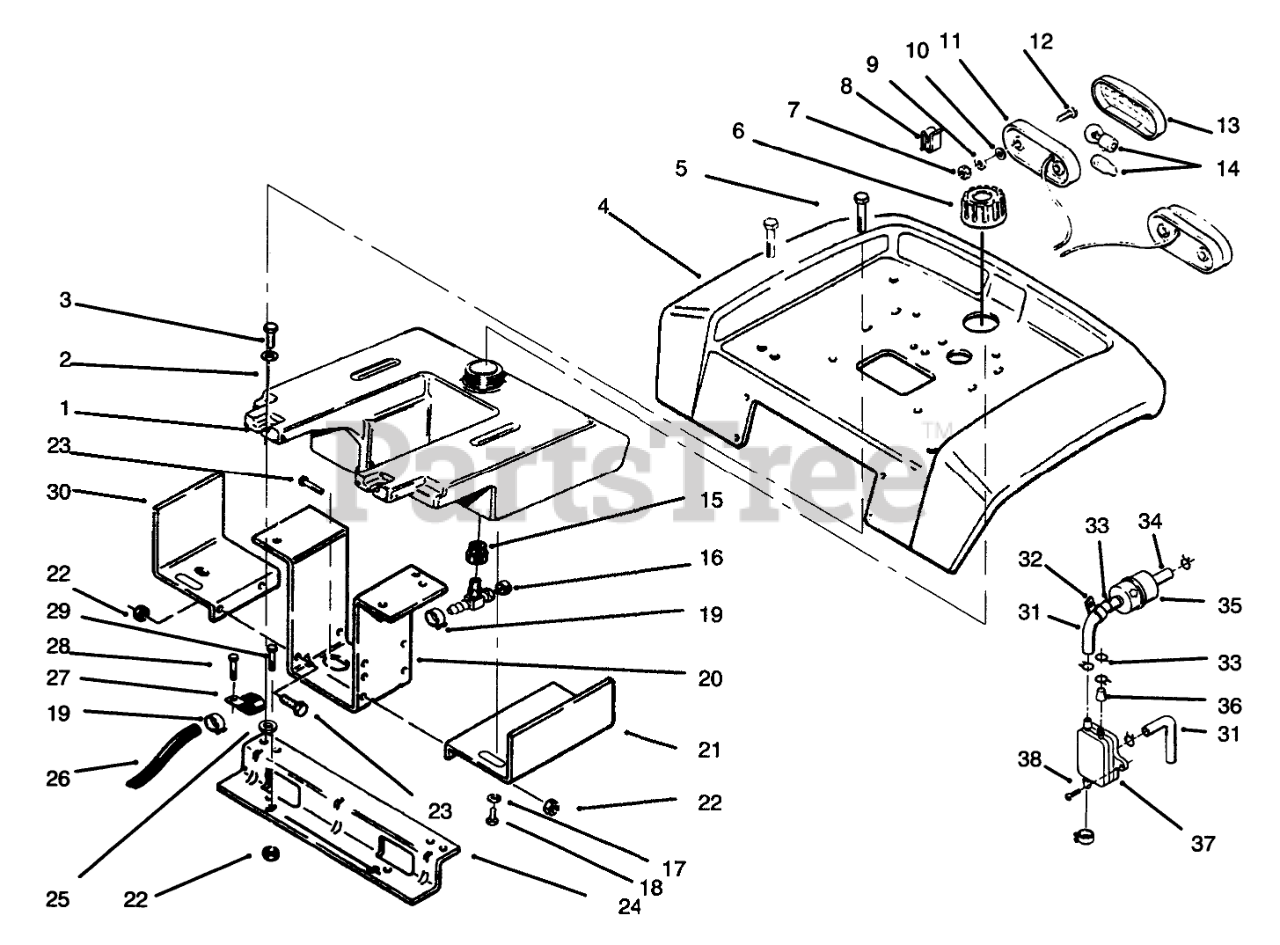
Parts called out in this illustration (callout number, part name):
1	Tank Asm-Fuel (Incl. Ref. #15-16)
2	WASHER-FLAT
3	SCREW-HWHTF
4	Fender
5	Bolt
6	GAS CAP ASM
7	NUT-LOCK, NI
8	SPEED CLIP
9	WASHER-FLAT
10	WASHER-LOCK, INT
11	BASE-TAIL LIGHT
12	Screw
13	LENS-TAIL LIGHT
14	Bulb
15	BUSHING
16	VALVE-FUEL
17	WASHER-LOCK
18	SCREW-HH
19	CLAMP-HOSE
20	Bracket-Fender
21	Fuel Tank Support LH
22	NUT-LOCK, NI
23	SCREW-HH
24	BRACKET-FENDER B
25	WASHER-PLAIN
26	Line-Fuel 62"
27	CLIP
28	SCREW-HH, LOCK
29	SCREW-HH
30	Support-FueITank RH
32	Clip
33	CLAMP
34	FUEL HOSE
35	FILTER-FUEL
36	CAP-FUEL OUTLET
37	PUMP-FUEL
38	Screw
